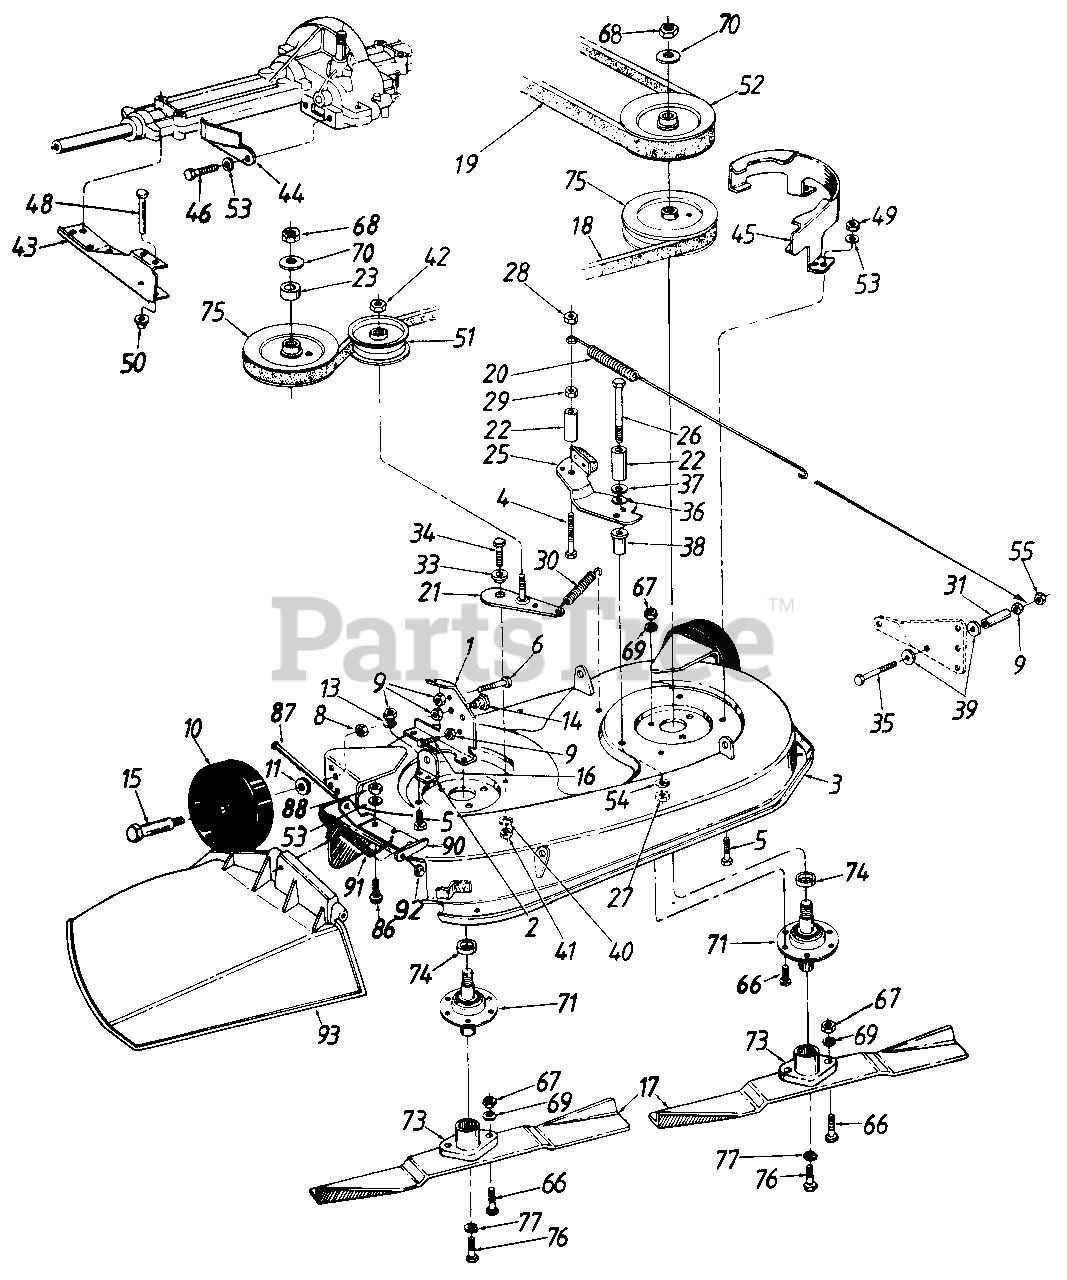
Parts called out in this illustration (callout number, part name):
1	Deck Disengagement Brkt.
2	Rear Deck Brkt.-R.H.
3	32" Deck Ass'y.
4	Hex Bolt 1/4-28 x 1.75" Lg.
5	Hex Bolt 1/4-20 x .62" Lg.
6	Hex Wash. Hd. Scr. 1/4-20 x 1.5" Lg.
8	Hex L-Nut 3/8-16 Thd.
9	Hex Nut 1/4-20 Thd.
11	Bell-Wash. .380" I.D. x .88"
13	L-Wash. 1/4" I.D.
14	Shld. Bolt .500" Dia. x .215"
15	Shld. Bolt .498" Dia. x 1.53"
16	Hex Tap Scr. 1/4-20 x .75" Lg.
17	R.H. High-Lift Blade
18	V-Belt
19	V-Belt
20	Extension Spring 15-5/8" Lg.
21	Idler Brkt. Ass'y.
22	Spacer 5/16" I.D. x 1/2" O.D. x 31 /32
23	Spacer .752" I.D. x 1.25" O.D.
25	Deck Brake Brkt. Ass'y.
26	Hex Bolt 5/16-18 x 3.25" Lg.
27	Hex Nut 5/16-24 Thd.
28	Hex L-Nut l/4-28 Thd.
29	Hex Nut 1/4-28 Thd.
30	Extension Spring 4.35" Lg.
31	Spacer 1/4" l.D. x 3/8" O.D. x 1-5/16"
33	Shoulder Spacer
34	Hex Bolt 3/8-16 x 1" Lg.
35	Hex Bolt 1/4-20 x 2.5" Lg.
36	Wave Washer
37	Shld. Spacer .27" Lg.
38	Spacer 1.46" Lg.
39	Flat Wash. 1/4"
40	L-Wash. 3/8" I.D.
41	Hex Nut 3/8-16 Thd.
42	Hex L-Nut 3/8-24 Thd.
45	Belt Guard Deck-R.H.
46	Hex Bolt 1/4-20 x .62" Lg.
49	Hex Nut 1/4-20 Thd.
50	Speed Nut 1/4" Rod
51	Flat Idler Pulley
52	5" Dia. Pulley
53	L-Wash. 1/4" I.D.
54	Bell-Wash. 5/16" l.D.
55	Hex L-Nut 1/4-20 Thd.
66	Hex Bolt 5/16-24 x 1" Lg.
67	Hex Nut 5/16-24 Thd.
68	Hex Jam Nut 5/8-18 Thd.
69	L-Wash. 5/16" l.D.
70	Bell-Wash. 5/8" l.D.
71	Blade Spindle Ass'y. Comp.
73	Blade Adapter
74	Spacer
75	5" Dia. Pulley
76	Hex Bolt 3/8-24 x l.0" Lg.
77	L-Wash. 3/8" l.D. H.D.
86	Truss.-Mach. Scr. 1/4-20 x .75" Lg.
87	Hinge Pin
88	Hex Nut 1/4-20 Thd.
90	Hinge Mtg. Brkt.
91	Torsion Spring
93	Chute Ass'y. Comp.
